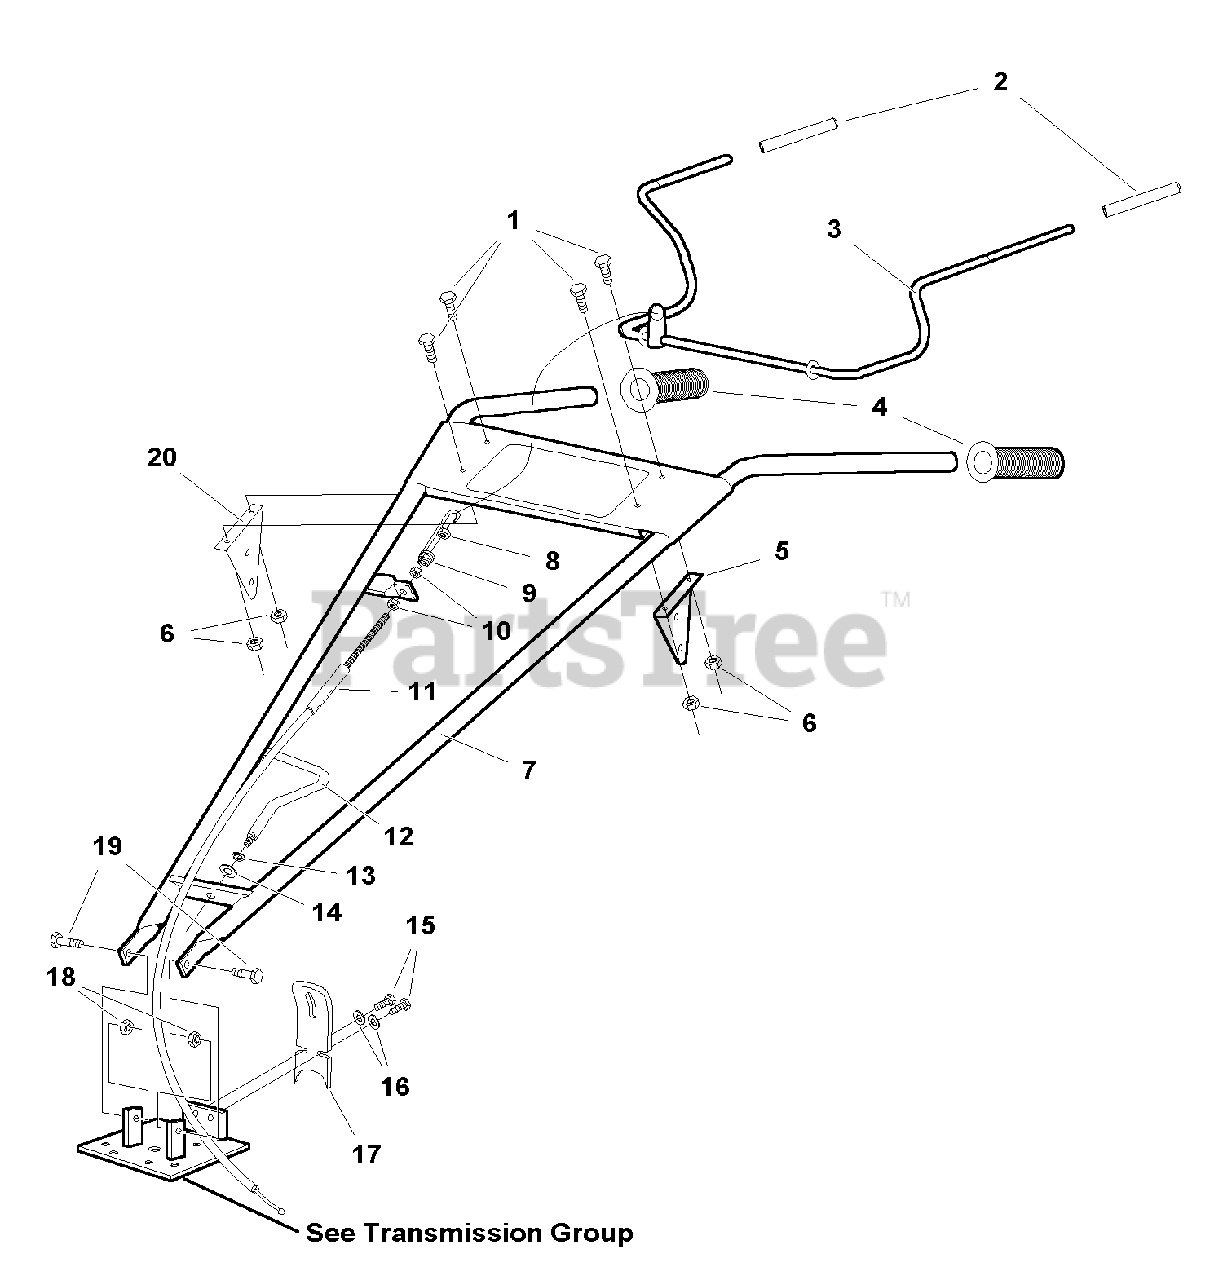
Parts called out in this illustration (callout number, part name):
1	CAPSCREW, Hex Head, 5MM X .8MM X 10MM
2	HANDLE GRIP, Drive Control Lever
3	LEVER, Drive Control
4	HANDLE GRIP
5	BRACKET, Drive Control Lever LH
6	NUT, Hex Nylok
7	HANDLE BAR ASSEMBLY, w/Tab
8	NUT, Hex Nylok
9	SPRING, Forward Cable Adjustment
10	NUT, Hex Jam, 5/16", 24NF, 2B
11	CABLE ASSEMBLY
13	LOCKWASHER, Spring 3/8"
14	WASHER, 3/8"
15	CAPSCREW, Hex Flange Head, 5/16"-18 x 3/4"
16	WASHER, 5/16"
17	PLATE, Height Adjust
18	NUT, Hex, 3/8"-16NC, 2B
19	CAPSCREW, 3/8"-16 x 1" G5
20	BRACKET, Drive Control Lever RH
